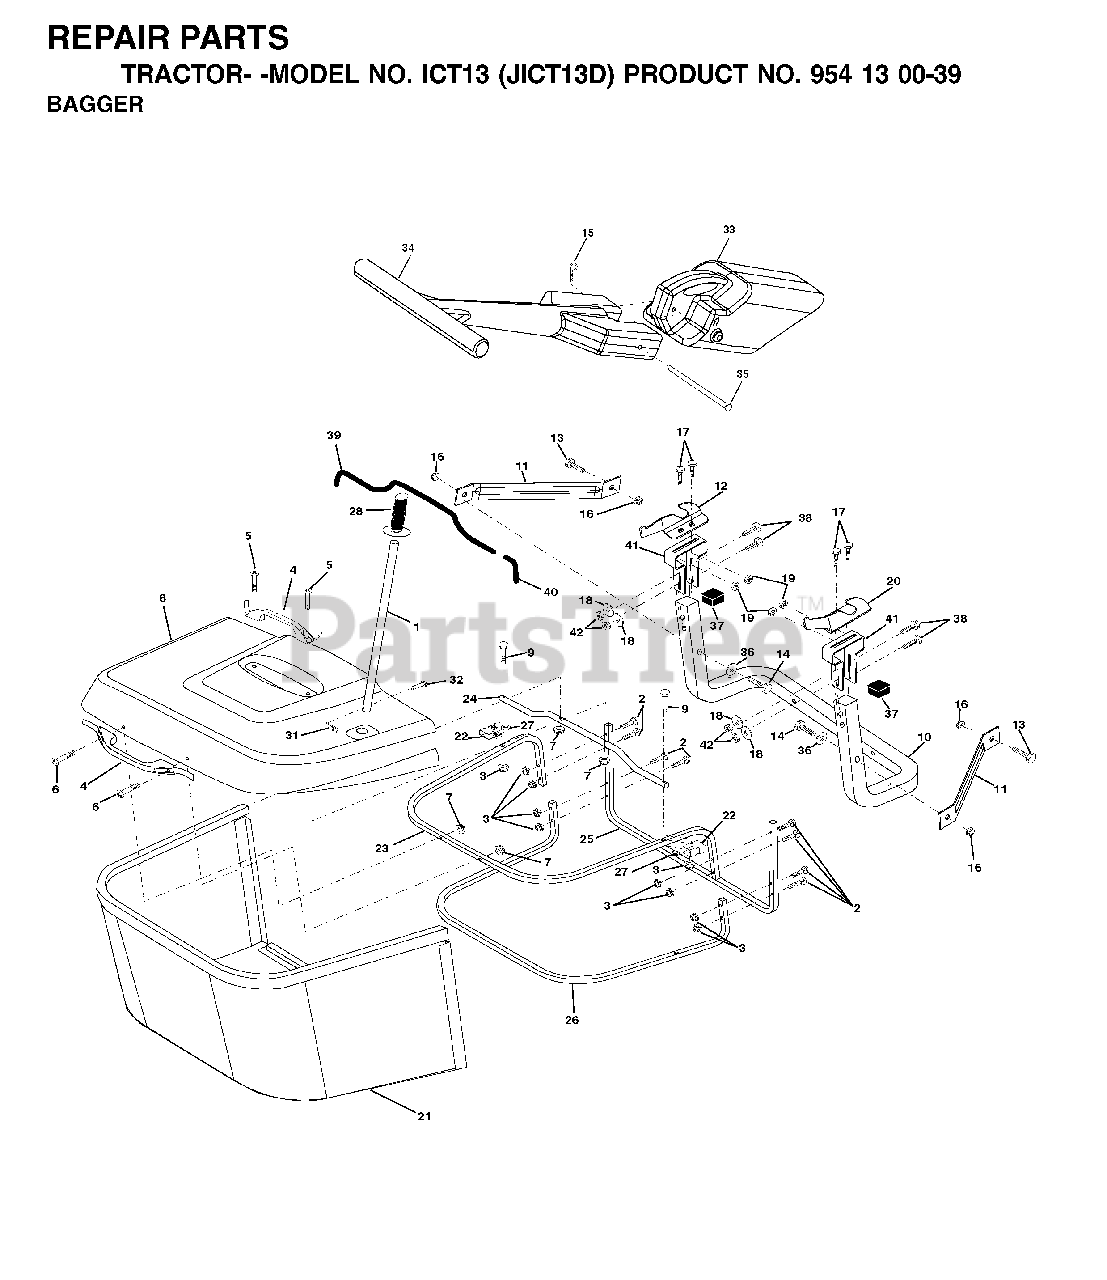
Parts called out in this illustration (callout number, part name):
1	TUBE HANDLE BAGGER
3	NUT T
5	SCREW.PAN.HEAD
10	TUBE
11	BRACKET
15	RETAINER-SPRNG RB
16	NUT LOCK FLG 3/8-16 UNC
17	BOLT
18	WASHER M
19	NUT LOCK HEX FLANGE 5/16-18
20	BRACKET
21	BAG
22	BRACKET
23	TUBE
24	TUBE
26	TUBE
31	RETAINER M
32	RIVET,DRILLED
33	PLUG
35	PIN
36	WASHER
38	BOLT.5/16-18X2.5
39	TRIM
40	TRIM
41	BRKT, BAGGER
42	NUT.71038.31-18.HEX.NYLOCK
